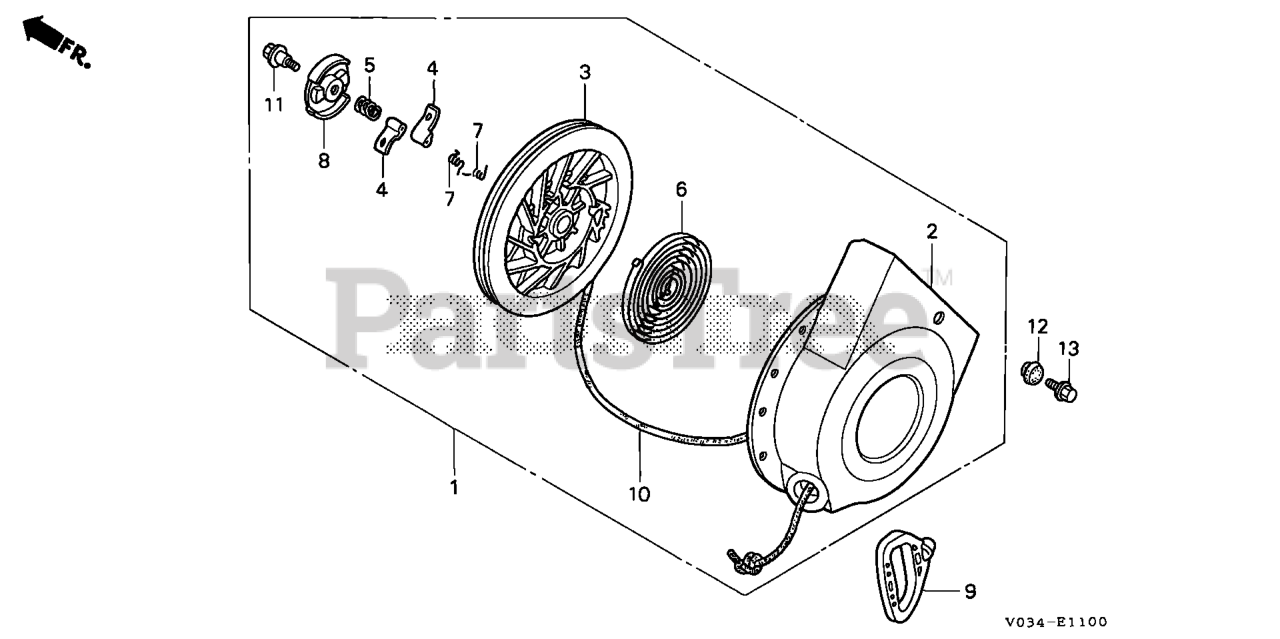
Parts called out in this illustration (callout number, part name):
1	STARTER ASSY., RECOIL *R280* (POWER RED)
2	CASE, RECOIL STARTER *R280* (POWER RED)
3	PULLEY, RECOIL STARTER
4	RATCHET, STARTER
5	SPRING, FRICTION
6	SPRING, STARTER RETURN
7	SPRING, RATCHET
8	RETAINER, SPRING
9	GRIP, STARTER
10	ROPE, RECOIL STARTER (NA USE ALT:08550-ZG921-11)
11	SCREW, CENTER
12	GROMMET B, CONTROL WIRE (16MM)
13	BOLT, FLANGE (6X10)
